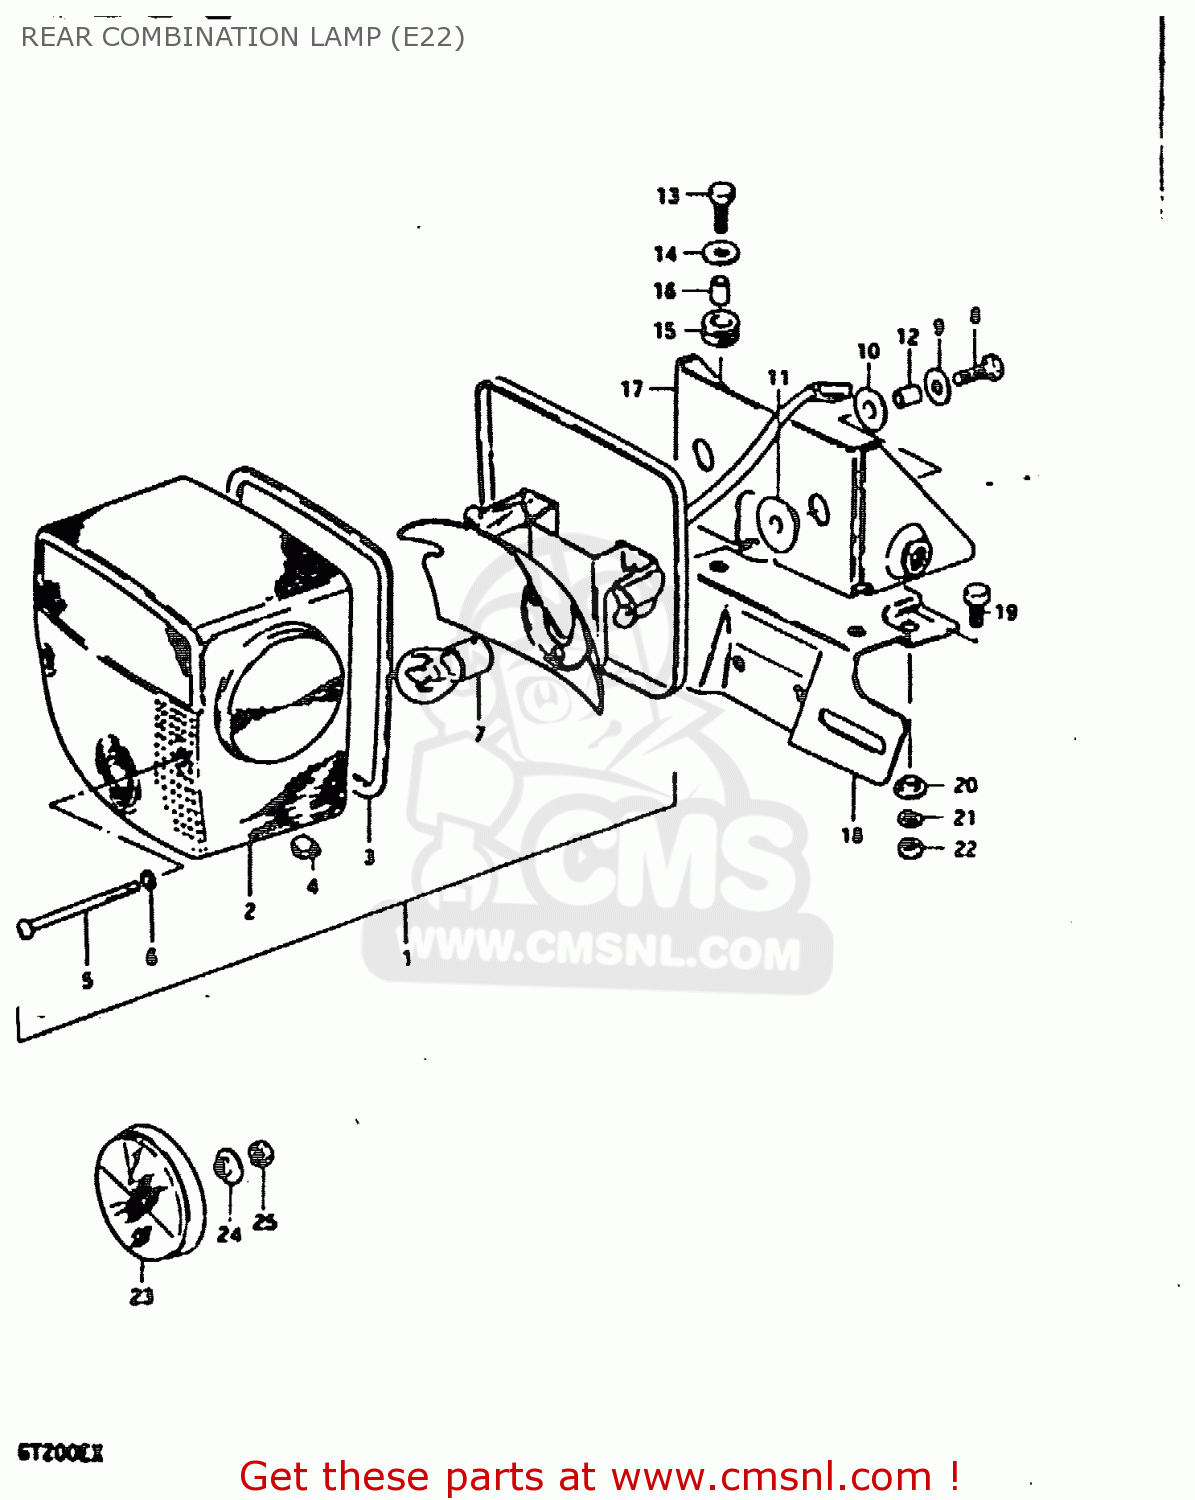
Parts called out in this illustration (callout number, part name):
1	LAMP ASSY, TAIL
2	LENS
3	GASKET (NAS)
4	GROMMET,REAR COMBINATION LAMP
5	SCREW (4X55)
6	GASKET (NAS)
7	BULB(12V21/5W)
8	BOLT
9	WASHER (6.5X20X1.2)
10	CUSHION
11	CUSHION
12	SPACER (6.8X10X11.5)
13	BOLT, UPPER
14	WASHER (6.5X20X1.2)
15	CUSHION
16	SPACER (6.1X9X9)
17	BRACKET, COMBINATION LAMP
18	PLATE, LICENSE
19	BOLT
20	SPACER
21	LOCK WASHER
22	NUT
23	REFLECTOR,REFLEX
24	SPACER
25	NUT
